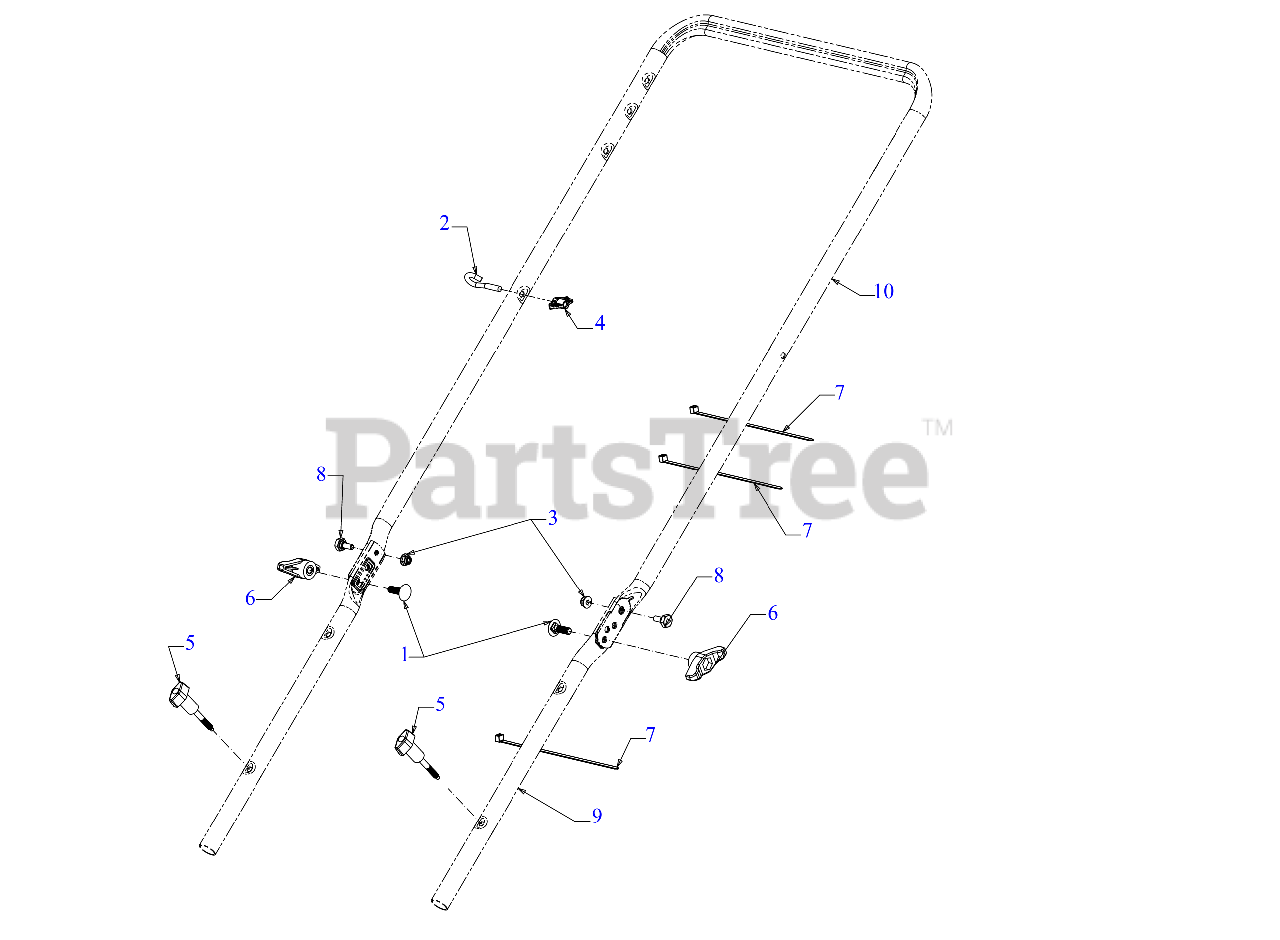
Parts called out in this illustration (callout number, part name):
1	SCREW 5/16-18 x 1.00 GR5
2	EYEBOLT 1/4-20
3	FLANGE LOCK NUT
4	HANDLE KNOB
5	WING KNOB 1/4-20
6	WING KNOB 5/16-18
7	7" CABLE TIE
8	SHOULDER SCREW
9	LOWER HANDLE (POWDER BLACK)
10	UPPER HANDLE
